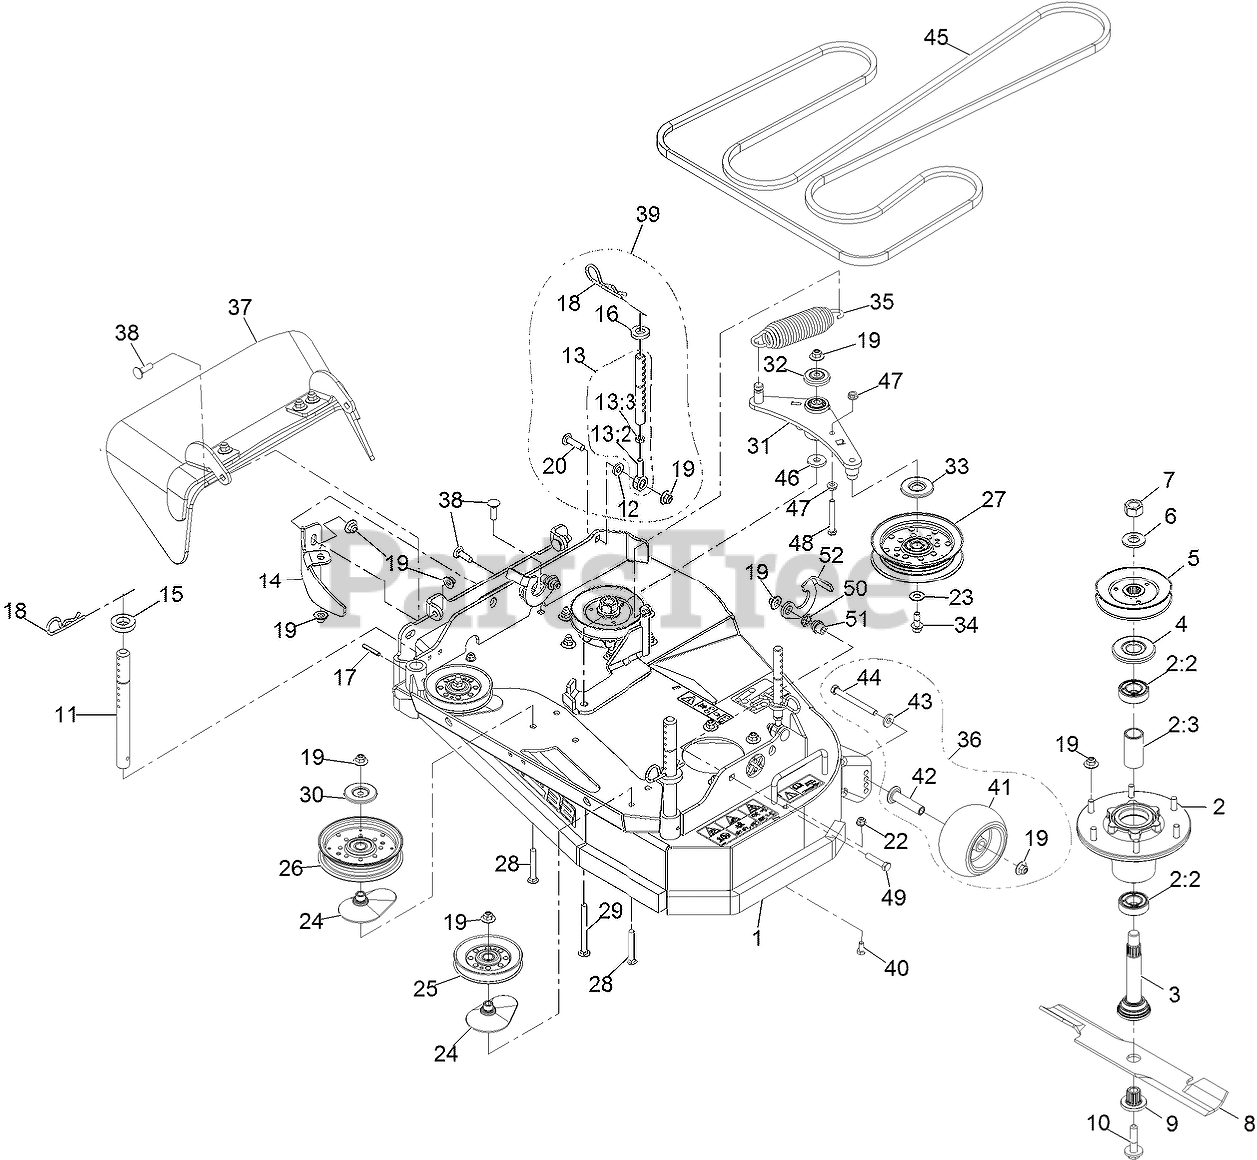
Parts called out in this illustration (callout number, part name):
1	ASM-Deck Decals 32
2	ASM-CUTTER HSG WITH BEARINGS
2:2	BEARING-BALL
2:3	SPACER-BEARING
3	ASM-SPINDLE AND SEAL
4	GUARD,BEARING TOP .989
5	SHEAVE-BLADE DRIVE
7	NUT-HEX
9	BUSHING,SPLINED
10	SCREW,SEMS 1/2-20 X 2.19
11	ROD, DECK SUPPORT
13	ASM, Support Link
13:2	BALLJOINT
13:3	NUT-HJ
14	BAFFLE, DOGLEG
15	SPACER-DECK SUPPORT
18	PIN-CUT HEIGHT
19	Nut-Nyloc 3/8-16 Flg
20	SCREW-CARR
22	NUT-HF, NI
23	WASHER-FLAT
24	SPACER-PULLEY
25	Idler - V 4.13 Eod-A
26	PULLEY-IDLER, FLAT
27	IDLER-PULLEY, FLAT
28	SCREW-CARR
29	SCREW-CARR
30	SHIELD-DUST
31	ASM.-Arm, Idler
32	GUARD-TOP
33	SHIELD-GUARD, DUST
34	SCREW-HFH
35	SPRING-EXTENSION
36	KIT-ANTISCALP ROLLER
37	Rubber Deflector ASM
38	BOLT-CARR
39	Kit-Support Link Svc
40	SCREW-HH
41	ROLLER-SCALP, ANTI
42	AXLE, ROLLER
43	WASHER-BELLEVILLE
44	SCREW-HH 3/8-16 X 3 3/4 GR 8
45	Belt-V
48	SCREW-HH
49	SCREW-HH
50	WASHER-SPRING
51	Bushing-Latch
52	Latch - Deck
